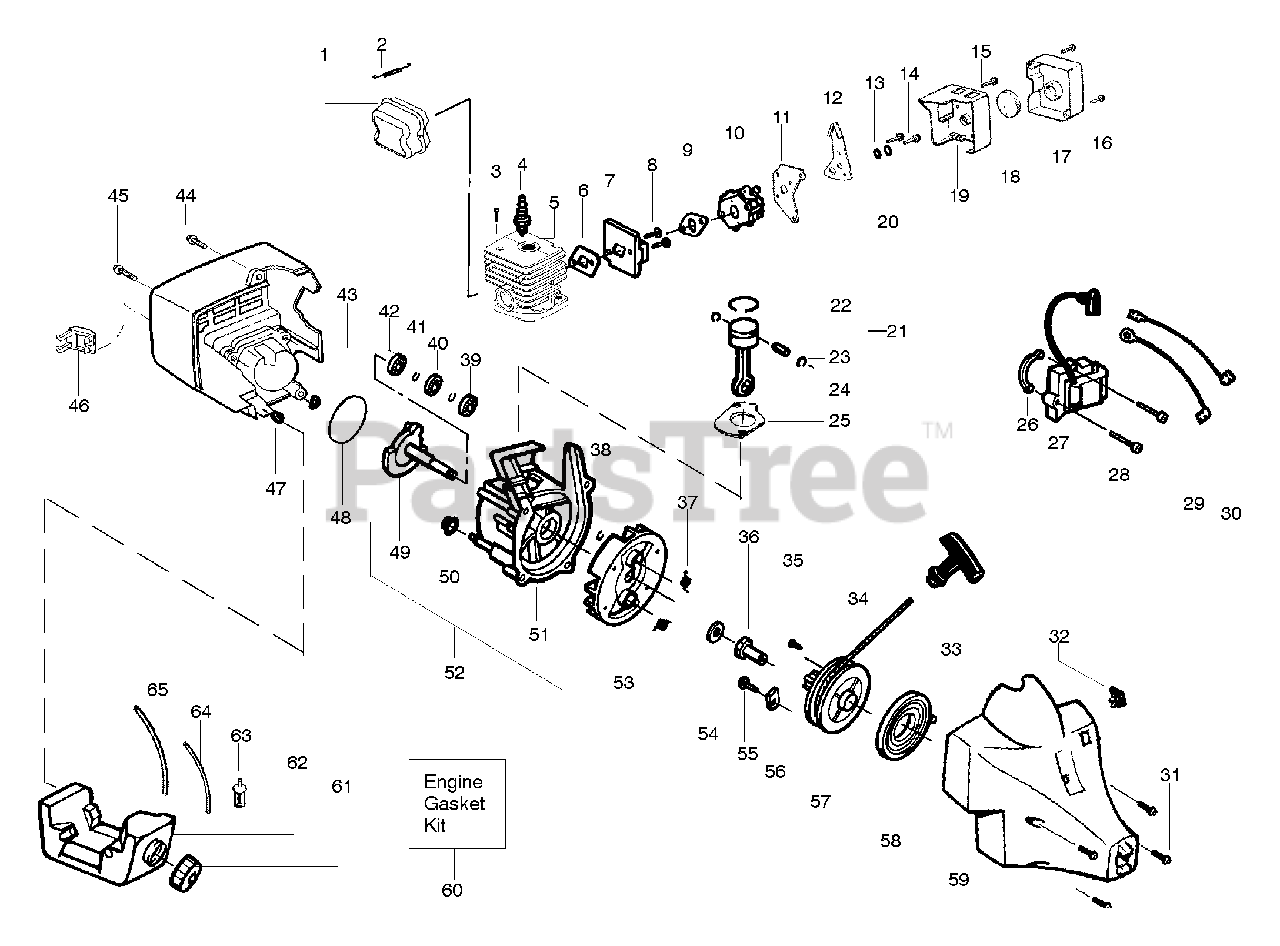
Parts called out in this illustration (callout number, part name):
1	Kit - Muffler
2	Muffler Spring
3	Screw-Cylinder
4	Spark Plug (RCJ 6Y)
5	Kit - Cylinder
6	Gasket-Cyl/Carb.(kit)
7	Adaptor-carb.
9	Gasket-Carb.(kit)
10	Kit - Carburetor Ass'y
11	Plate-Choke Mounting
12	Lever-Choke
17	Cover-Air Box
18	Foam-Air Filter
20	Spacer-Choke
21	Kit - Piston
22	Piston Ring
23	Retainer-Piston Pin
24	Assy-Connecting Rod
25	Gasket-Cylinder(kit)
26	Spacer-Module
27	Ignition Module
29	Assy-Ground Wire
30	Assy-Leadwire
31	Screw
32	Kit-Momentary Switch
33	Handle-Starter
34	Kit - Rope
36	Coupling-Drive
37	Spring-Starter Dog
38	Retain. Ring-C'shaft
39	Bearing-Outer
40	Seal-C'case
41	Retainer Ring-C'case
42	Bearing-Inner
45	Screw
46	Guard-Muffler
47	Isolator-Shroud
48	O-Ring-C'case(kit)
49	Assy-Crankshaft
50	Isolator-Crankcase
51	Assy-Crankcase
52	Assy-C'case & C'shaft
53	Assy-Flywheel
54	Washer-Flat
56	Retainer-Can
57	Kit-Starter Pulley
58	Spring-Starter
59	Assy-Fan Housing
60	Kit-Engine Gasket
61	Assy-Fuel Cap
62	Assy-Fuel Tank
63	Assy-Fuel Pickup
64	Kit-Fuel Line
65	Kit-Fuel Line
